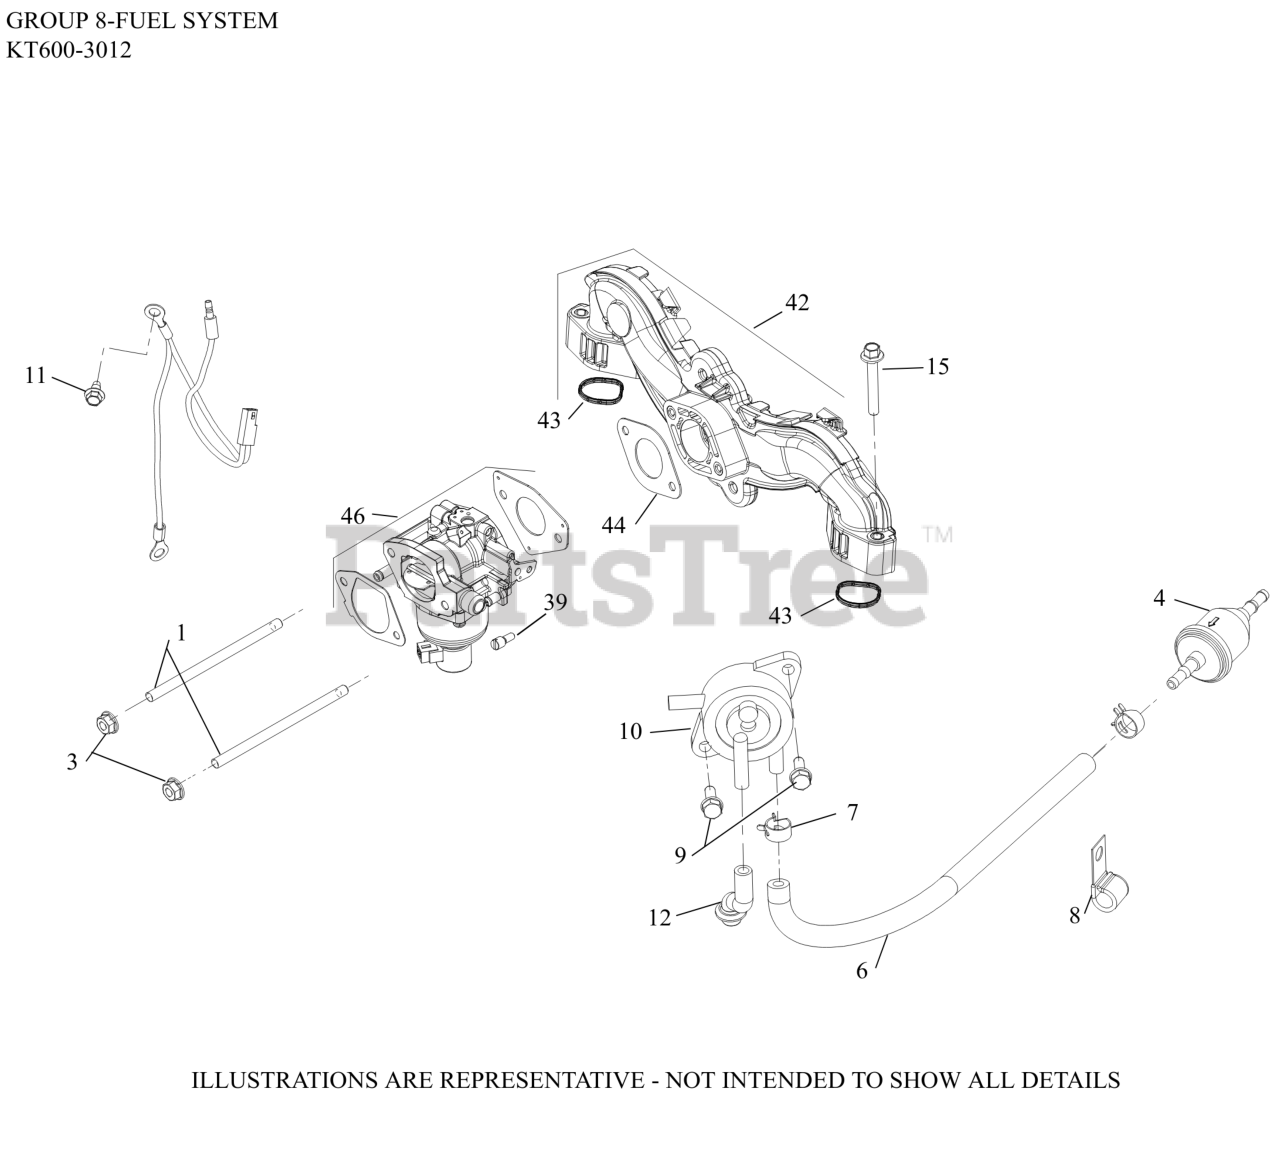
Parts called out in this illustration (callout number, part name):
3	NUT, FLG M6X1.0
4	FILTER,FUEL 51 MICRON (FUEL PUMP)
6	HOSE,LW PERM.FUEL 24.00"-USE 25 111 81-S
7	SPRING CLAMP, HOSE
8	CLIP, CABLE (KM)
9	SCREW, TAP M6X1.7X18
10	PUMP, FUEL (PULSE)-(#2539326S)
11	SCREW, THREAD FORMING
12	HOSE, PULSE PUMP(STEEL COVERS)
15	SCREW, FLG M6X1.0X40
39	SCREW, THROTTLE STOP
42	INTAKE MANIFOLD W/GASKETS
43	O-RING, INTAKE PORT
44	GASKET, CARBURETOR (PIM, CV)
46	KIT,CARB (NIKKI)
NI	KIT, HIGH ALT (19MM) NIKKI G-TYPE TWIN
NI	KIT, OVERHAUL NIKKI G-TYPE TWIN
NI	KIT, BOWL WITH O-RINGS NIKKI G-TYPE TWIN
NI	KIT, FLOAT AND NEEDLE NIKKI G-TYPE TWIN
NI	KIT,CHOKEREPAIR(SELF REL.)NIKKI G-TYPE T
NI	KIT,THROTTLE SHAFT(19MM)NIKKI G-TYPETWIN
